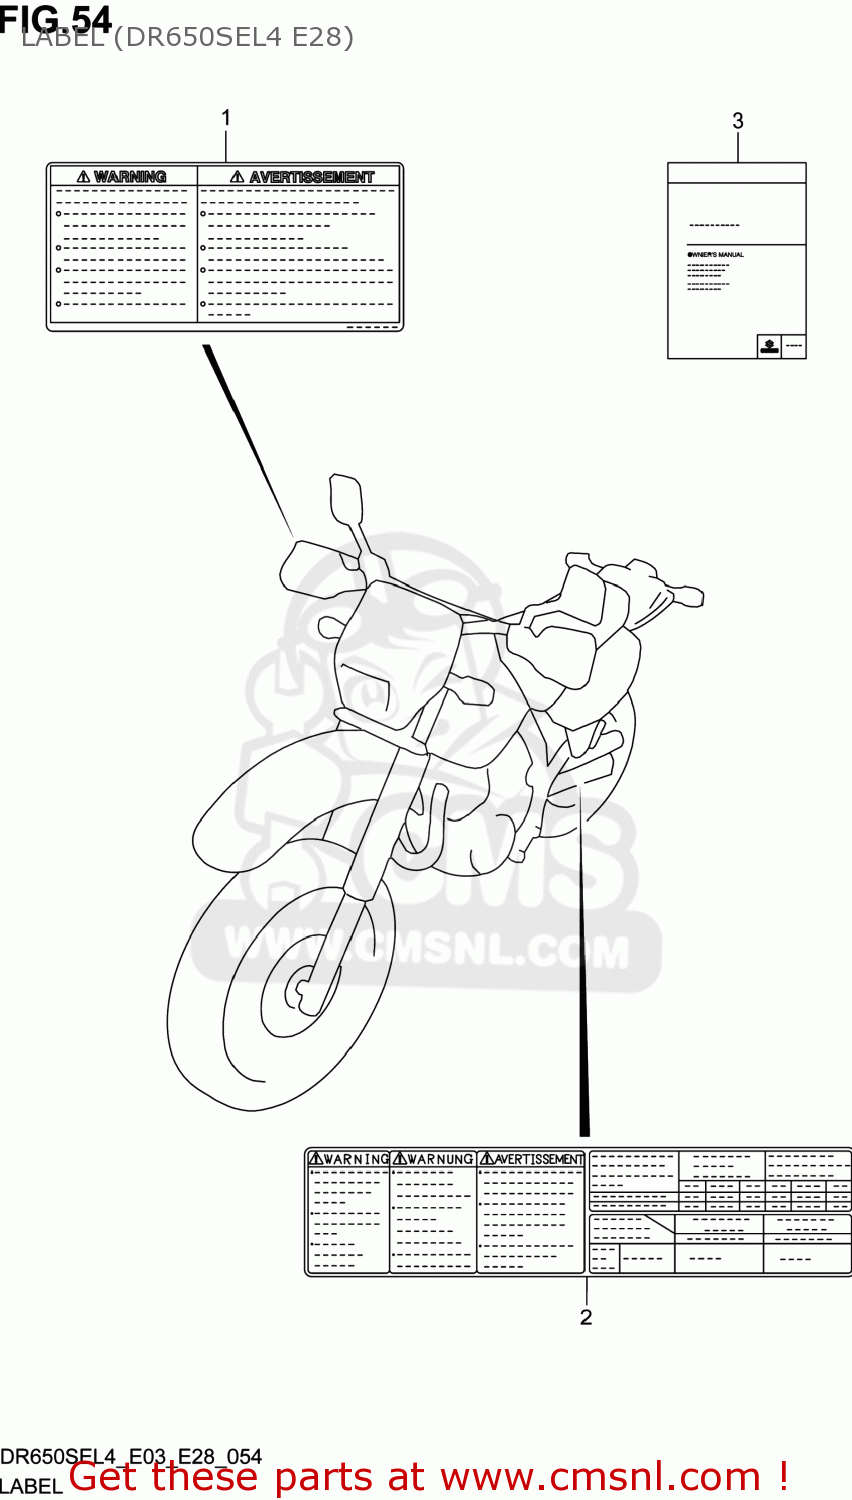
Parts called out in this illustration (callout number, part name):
1	LABEL,GENERAL WARNING
2	LABEL,TIRE INFORMATION
3	MANUAL,OWNER'S
